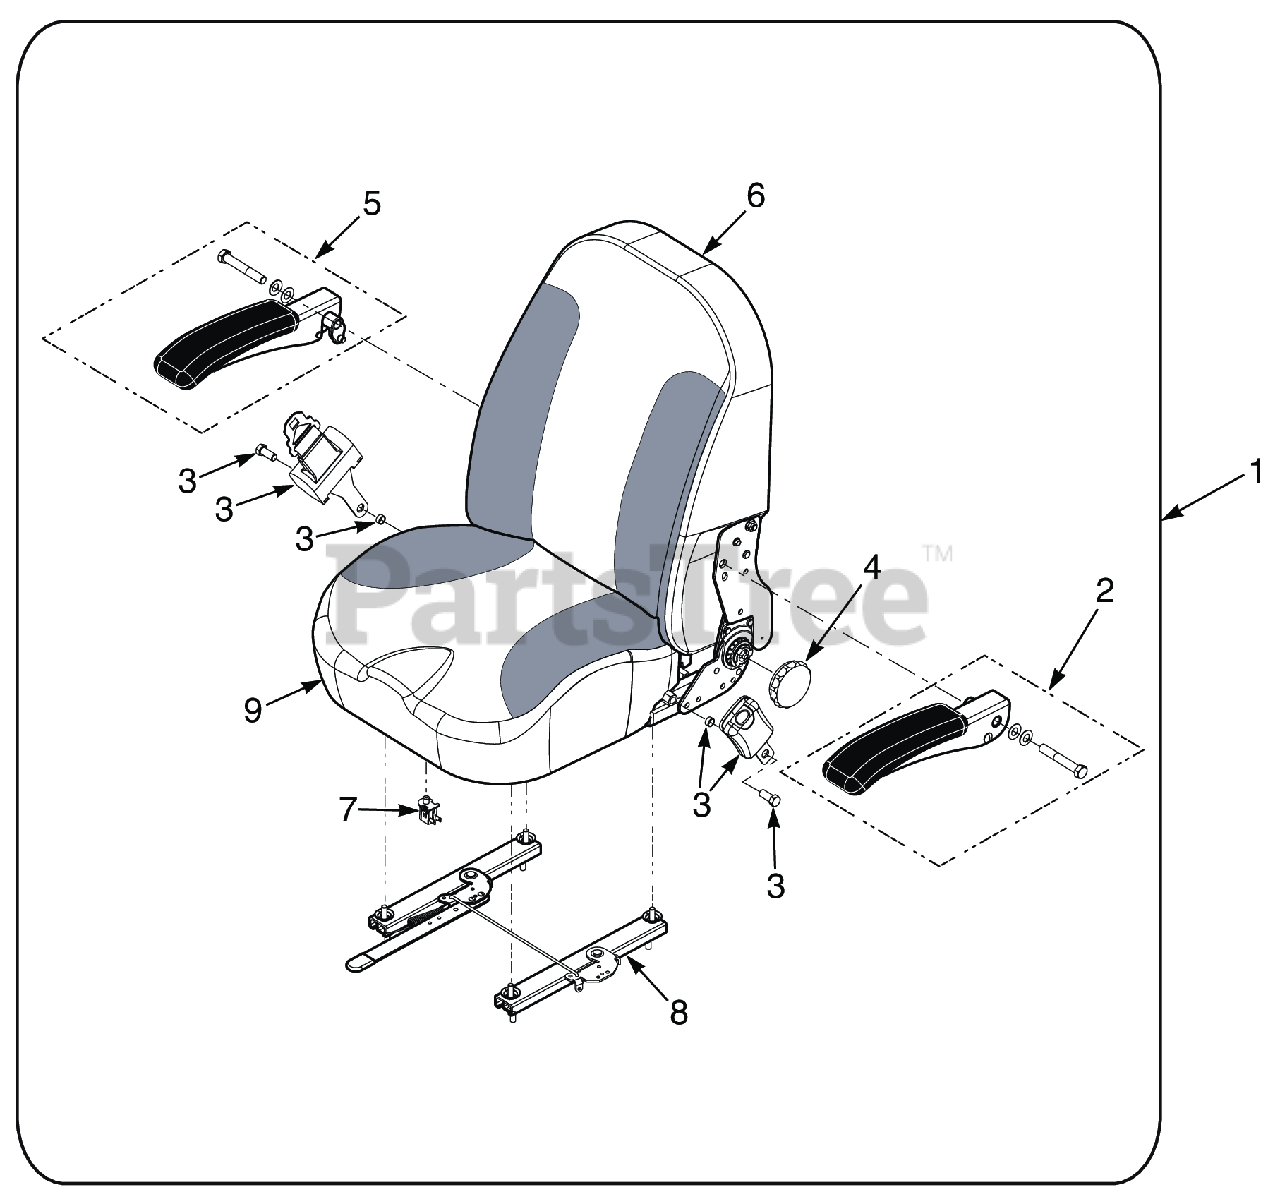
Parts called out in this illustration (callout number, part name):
1	Seat Assembly - SCZ
2	Armrest Kit, LH
3	Seat Belt Kit, Retractable - SCZ
4	Recliner Knob
5	Armrest Kit, RH
6	Back Cover
7	Switch, Interlock, Normally Open
8	Track Kit
9	Cushion Cover
